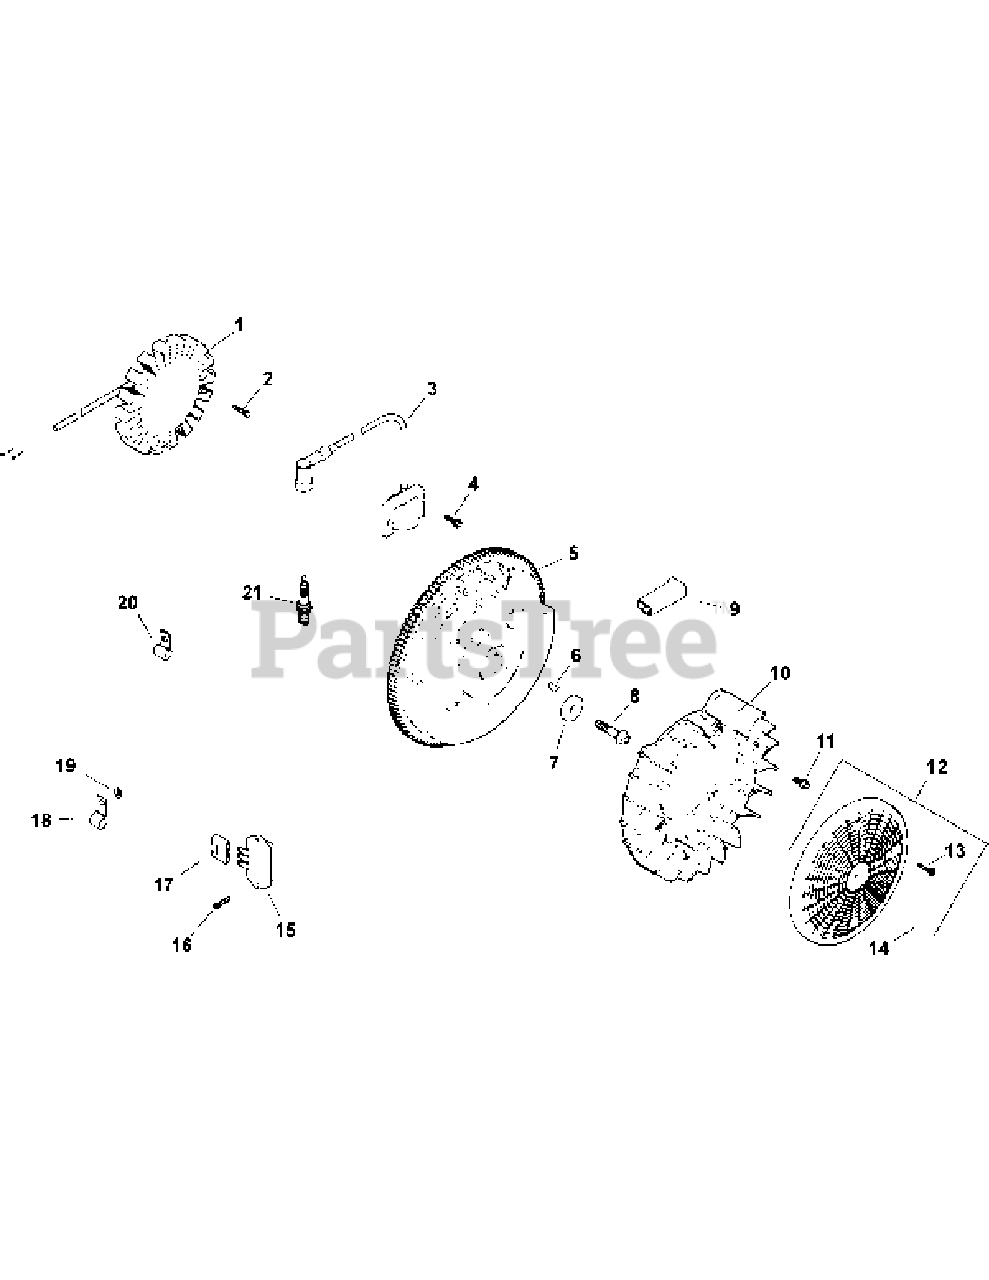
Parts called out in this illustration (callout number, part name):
1	KIT, 15 AMP STATOR
2	SCREW, THD FRM M5X.8X25
3	KIT, MODULE IGNTN (CDI FIXED)
4	SCREW, FLG THD FRM M5X.8X20
5	FLYWHEEL, ASSEMBLY (CV/CH670 & 730)
6	KEY, 3/16" X 5/8"
7	WASHER, FLAT 13/32"
8	SCREW, FLG M10X1.5X45
9	CONNECTOR (1 CONTACT)
11	BOLT, SHOULDER
12	KIT, GRASS SCREEN
13	SCREW, FLG SEMS M4X.7X25
14	DECAL, GRASS SCREEN
15	RECTIFIER-REGULATOR
16	SCREW, HEX FLANGE HI-LO
17	CONNECTOR (3 CONTACT)
18	CLIP, CABLE
19	WASHER, FLAT 1/4"
21	PLUG, SPARK
